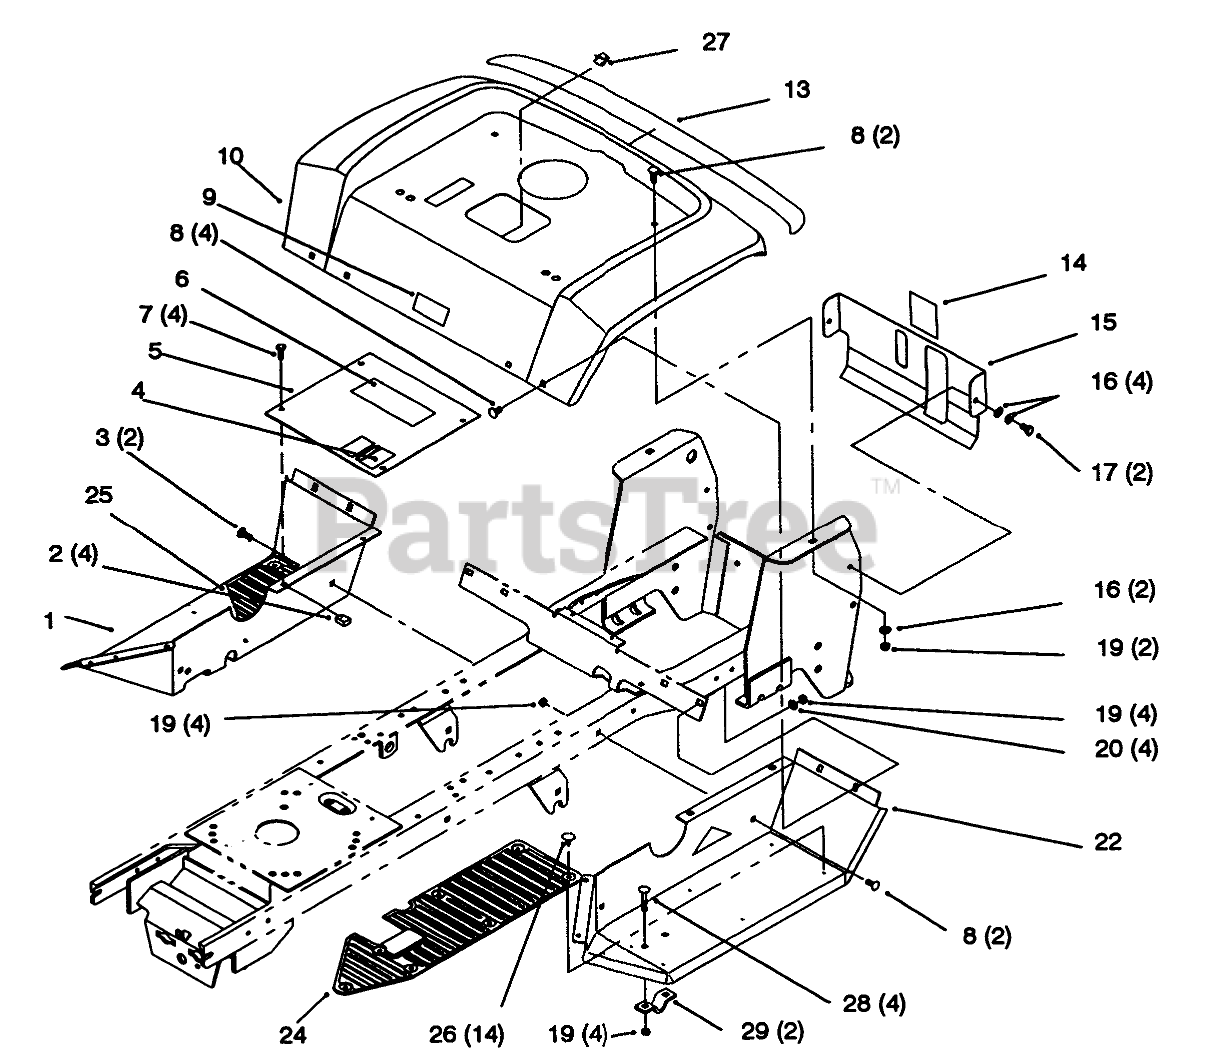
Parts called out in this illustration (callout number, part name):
1	Footrest-RH (Only On: 72042, 72062)
1	Footrest-RH (Only On: 72043, 72103, 72063, 72083)
2	Nut-Retainer
3	SCREW-CARR
4	Decal-HOC (Only On: 72042, 72043, 72083)
4	Decal-HOC (Only On: 72103, 72063, 72062)
5	PLT - FTREST W/DECAL
6	DECAL-DANGER
7	SCREW-HH
8	BOLT-CARR
9	Decal-USA (Only On: 72042, 72043, 72083)
13	DECAL - REAR FENDER
14	DECAL-LEVEL, FUEL
15	COVER-REAR
16	WASHER-PLAIN
17	SCREW
19	NUT-LOCK, NI
20	WASHER-FLAT
22	Footrest-LH (Only On: 72042, 72062)
22	Footrest-LH (Only On: 72043, 72103, 72063, 72083)
24	Mat-Foot RH (Only On: 72043, 72103, 72063, 72083)
24	Mat-Foot RH (Only On: 72042, 72062)
25	Mat-Foot LH (Only On: 72043, 72103, 72063, 72083)
25	Mat-Foot LH (Only On: 72042, 72062)
26	FASTENER-PANEL
27	CLIP-RETAINER, WIRE
28	SCREW-CARR
29	CLAMP
